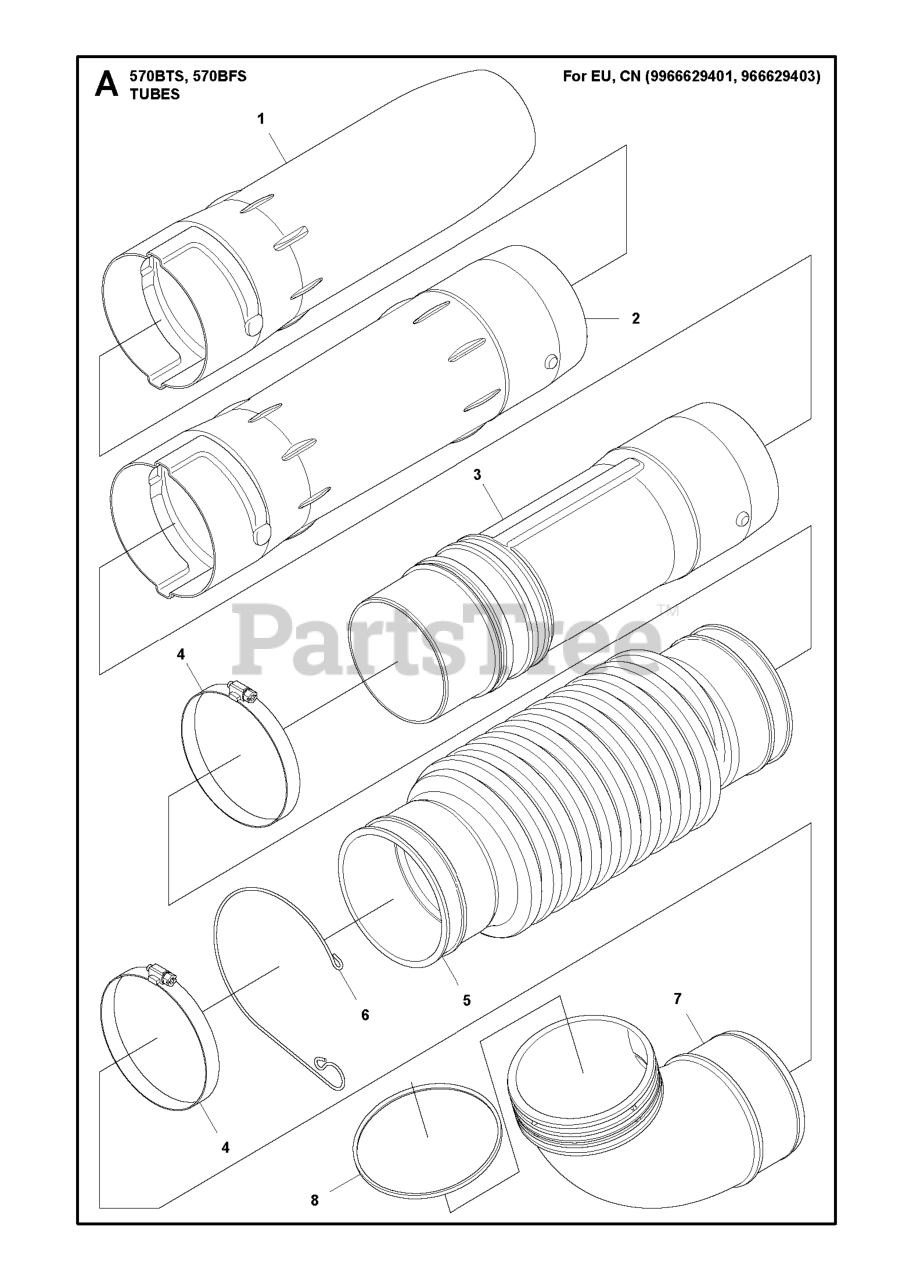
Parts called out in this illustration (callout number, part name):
2	PIPE STRAIGHT
3	SWIVEL JOINT
4	CLAMP(F115)
5	HOSE
7	PIPE ELBOW
